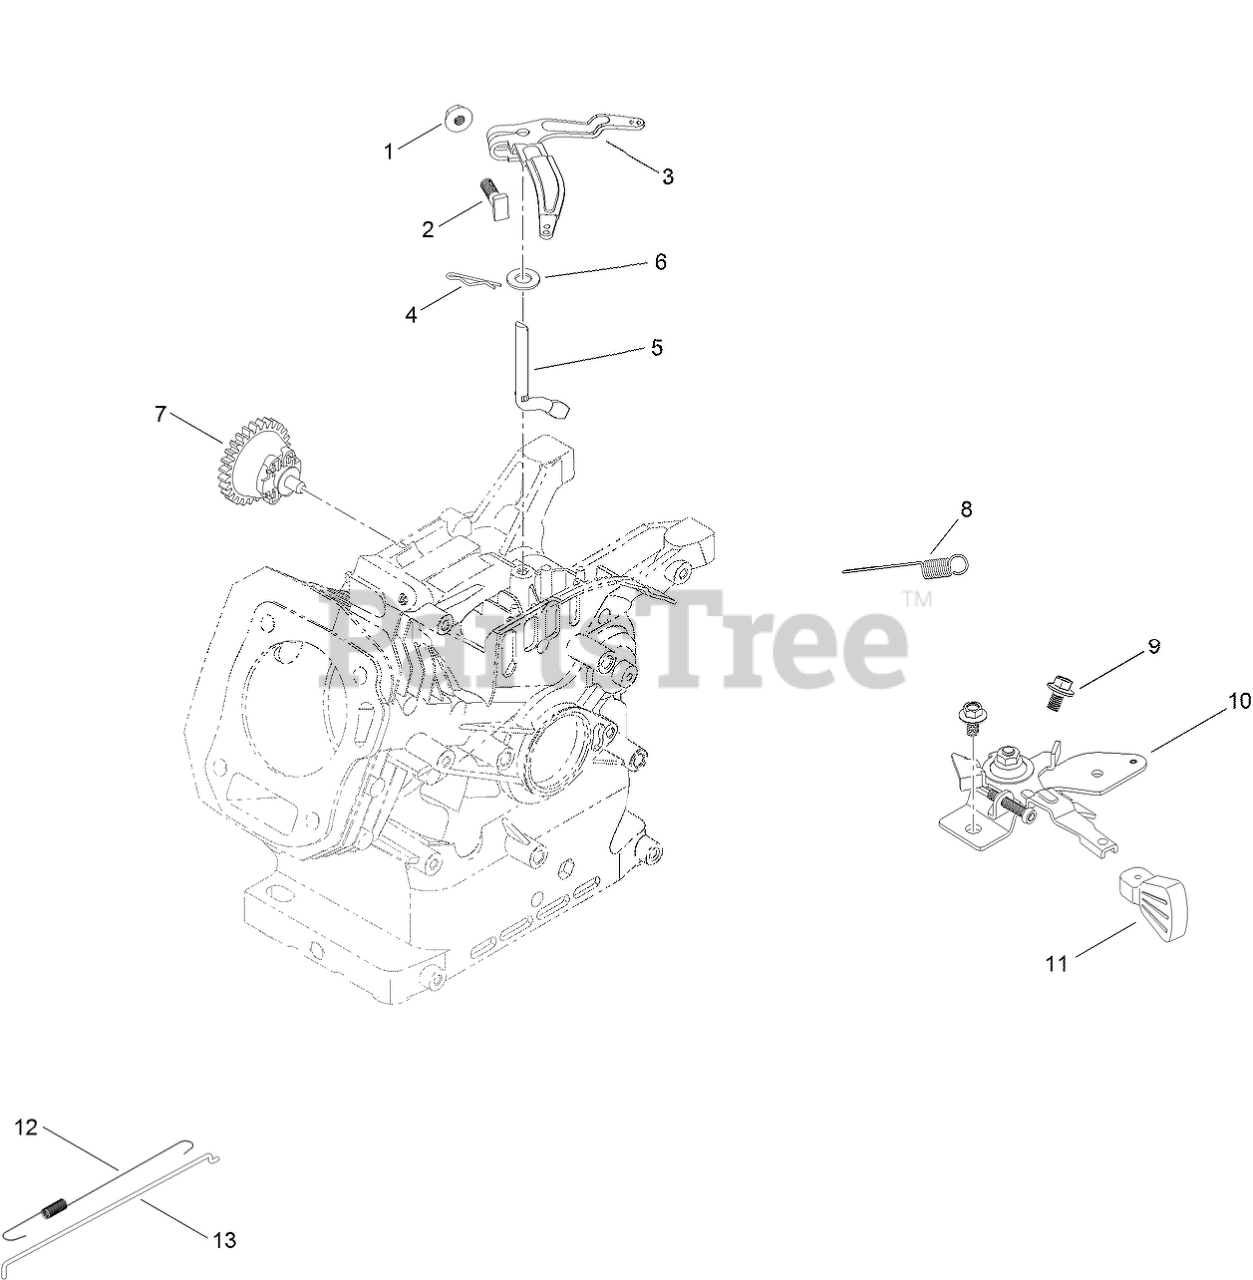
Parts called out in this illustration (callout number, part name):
1	NUT-FLANGE
2	BOLT-ARM, GOVERNOR
3	ARM-GOVERNOR
4	PIN-HAIR
5	SHAFT-GOVERNOR
6	WASHER-PLAIN
7	GOVERNOR GEAR ASM
8	SPRING-GOVERNOR
9	SCREW-HHF
10	SPEED CONTROL ASM
11	KNOB-CONTROL, THROTTLE
12	SPRING-RETURN, THROTTLE
13	ROD-GOVERNOR
